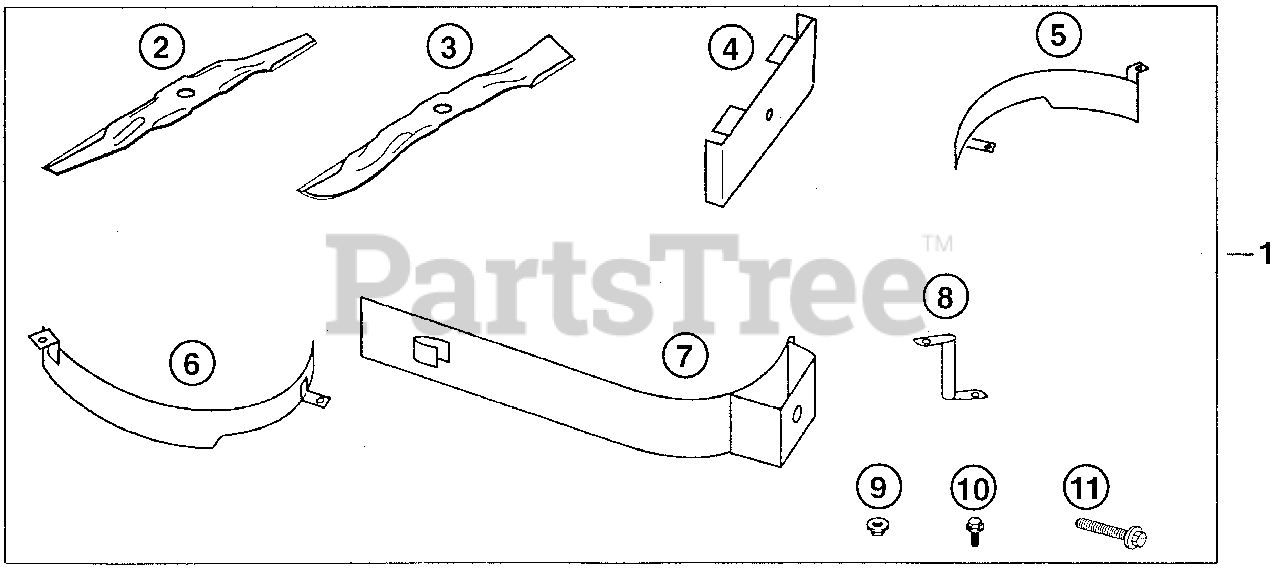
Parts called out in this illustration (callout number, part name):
1	MULCH KIT (46") (NOT AVAILABLE)
2	BLADE, LOW-LIFT
3	BLADE, ROTARY
4	PLATE, DISCHARGE
5	GUIDE A, SWIRL
6	GUIDE B, SWIRL
7	GUIDE C, SWIRL
8	ROD, SWIRL
9	NUT, HEX. (8MM)
10	BOLT, FLANGE (8X15) (NOT AVAILABLE)
11	BOLT, FLANGE (10X15) (NOT AVAILABLE)
